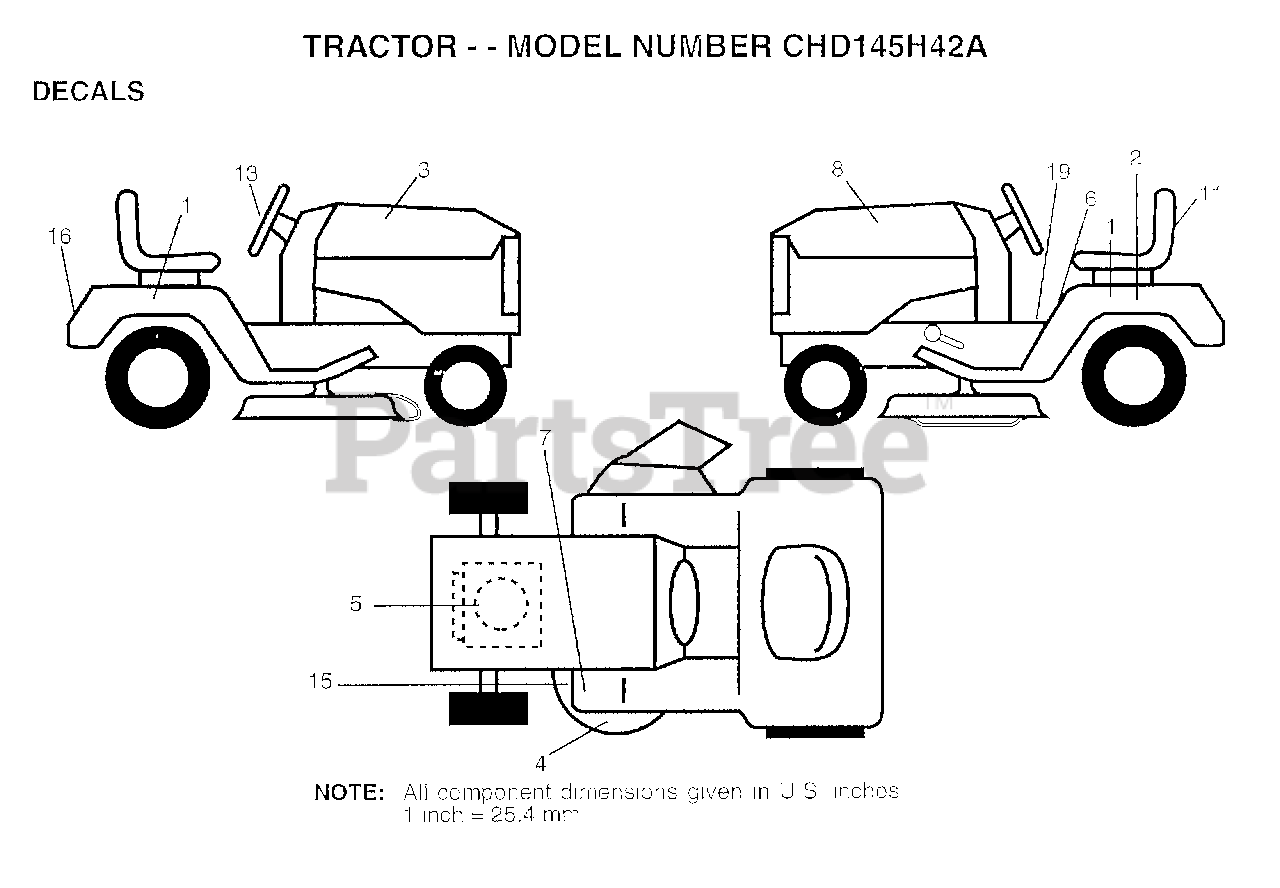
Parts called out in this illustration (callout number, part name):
1	"DECAL FENDER,SD"
2	DECAL.BATRY.3-3908
3	"DECAL-HOOD,RH"
4	"DECAL DECK,MULCH"
5	"DECAL REPLCMT,ENG"
6	DECAL.CAUT.ENG/FR
7	DECAL T
8	"DECAL-HOOD,LH"
11	"DECAL SEAT,ACC"
13	"DECAL WHEEL,STEER"
15	DECAL
16	"DECAL FENDER,LOGO"
19	DECAL SADDLE OPER
